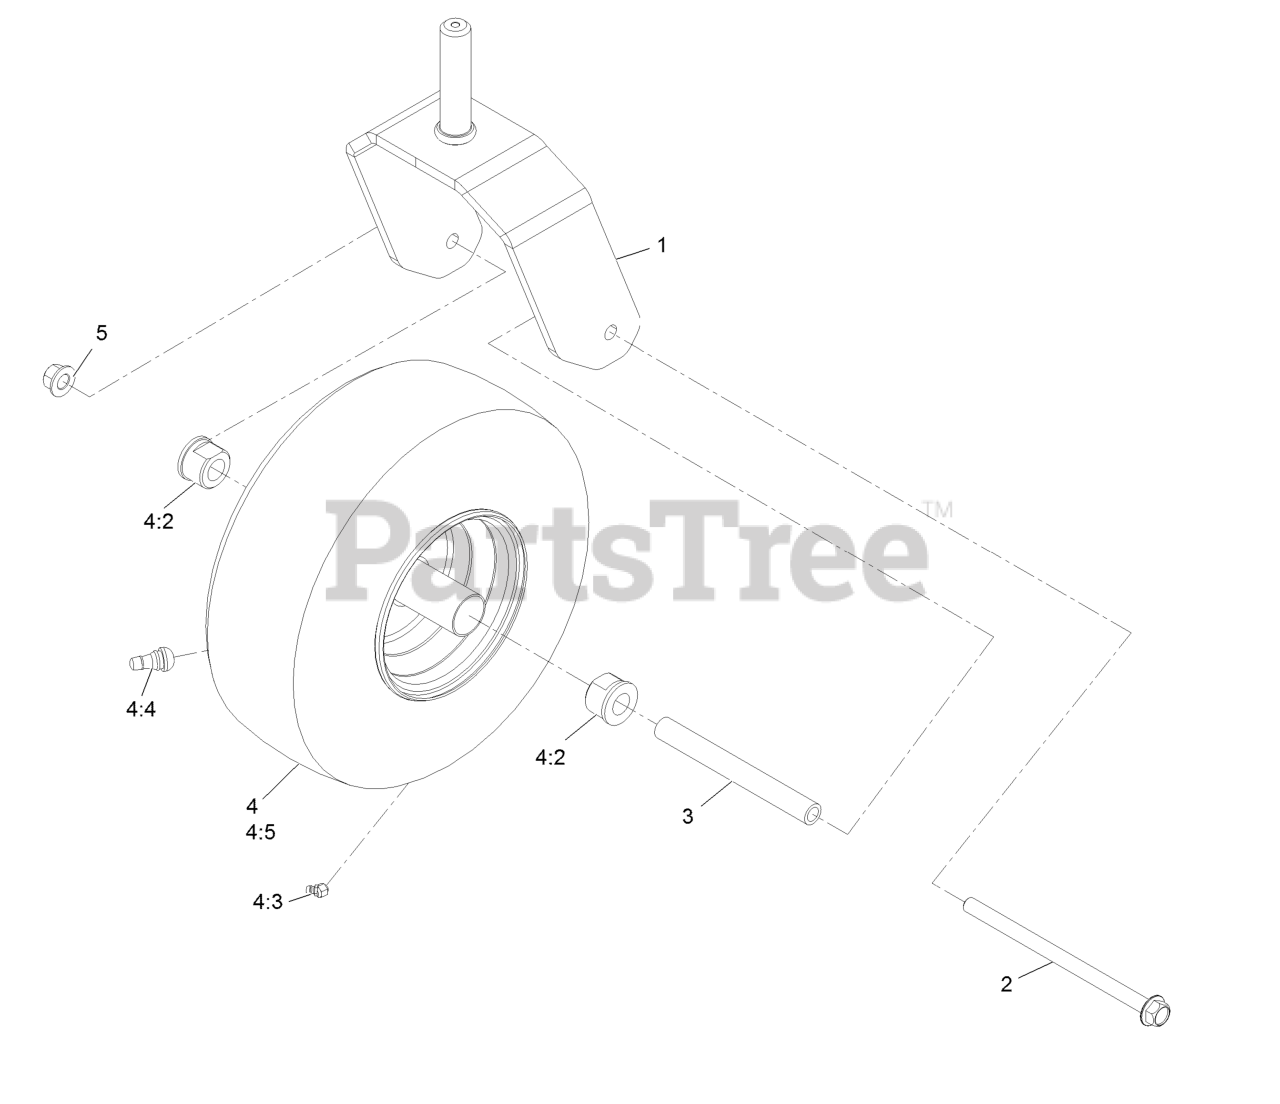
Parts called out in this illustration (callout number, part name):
1	Fork-Caster
2	Screw-HHF
3	Spanner-Wheel, Caster
4	ASM, Tire & Wheel
4:2	Bushing-Flange
4:3	Fitting-Zerk
4:4	Valve
5	Nut-Lock 1/2-13
